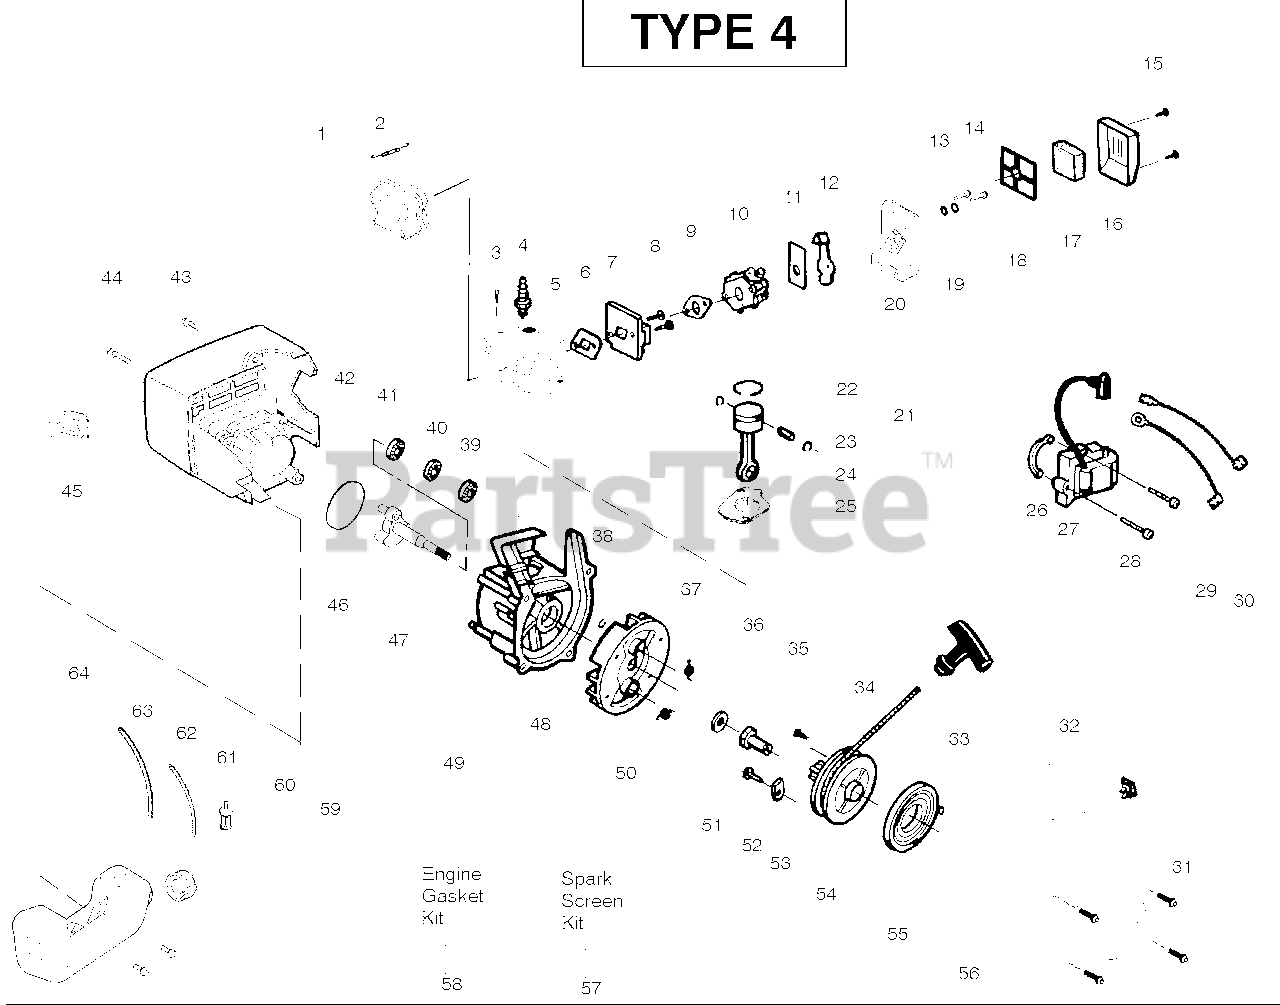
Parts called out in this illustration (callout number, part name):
1	Kit - Muffler
2	Muffler Spring
3	Screw-Cylinder
4	Spark Plug (RCJ 6Y)
5	Kit - Cylinder
6	Gasket-Cyl/Carb.(kit)
7	Adaptor-carb.
9	Gasket-Carb.(kit)
10	Kit-Carb. (WA-226)
11	Plate-Choke Mounting
16	Cover-Air Box
17	Foam-Air Filter
18	Plate-Air Filter Support
21	Kit - Piston
22	Piston Ring
23	Retainer-Piston Pin
24	Assy-Connecting Rod
25	Gasket-Cylinder(kit)
26	Spacer-Module
27	Ignition Module
29	Assy-Ground Wire
30	Assy-Leadwire
31	Screw
33	Handle-Starter
36	Coupling-Drive
37	Spring-Starter Dog
38	Retain. Ring-C'shaft
39	Bearing-Outer
40	Kit-Seal C'case
41	Bearing-Inner
44	Screw
45	Guard-Muffler
46	O-Ring-C'case(kit)
47	Assy-Crankshaft
48	Assy-Crankcase
49	Assy-C'case & C'shaft
50	Assy-Flywheel
54	Kit-Starter Pulley
55	Spring-Starter
56	Assy-Fan Housing
57	Kit-Spark Screen
58	Kit-Engine Gasket
59	Retainer-Tank
60	Assy-Fuel Cap
61	Assy-Fuel Pickup
62	Kit-Fuel Line
63	Kit-Fuel Line
64	Assy-Fuel Tank
